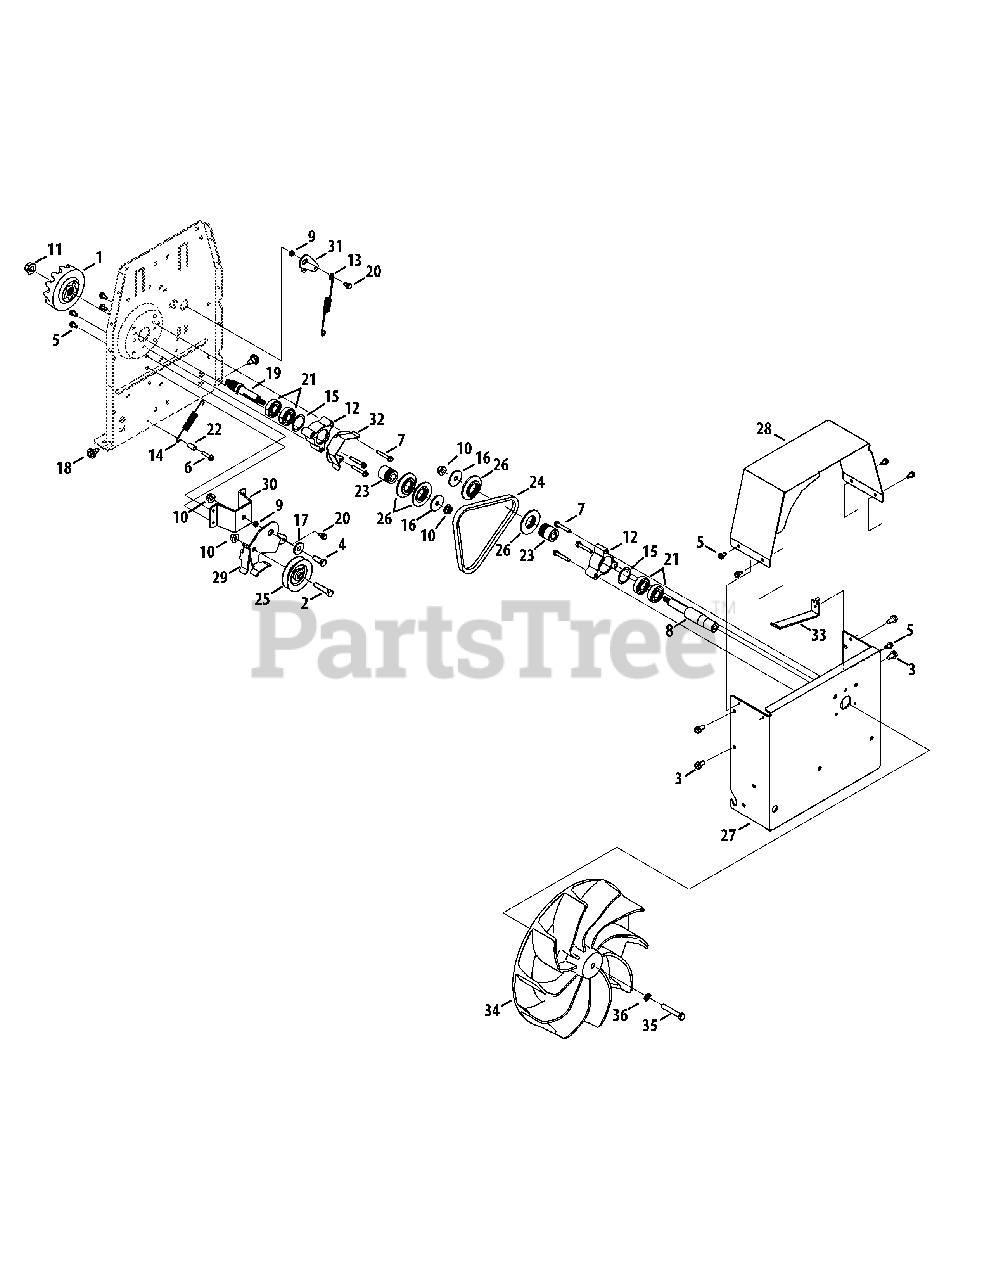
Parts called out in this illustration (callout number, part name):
1	Clutch Assembly
2	Hex Cap Screw, 3/8-16 x 1.75
3	Hex Washer Screw, 5/16-18 x .750
4	Hex Cap Screw, 3/8-16 x 1.0
5	Hex Washer Screw, 1/4-20 x .500
6	Self-tapping Screw, 1/4-20 x 1.00
7	Self-tapping Screw, 1/4-20 x 1.625
8	Spindle Shaft
9	Hex Lock Nut, 1/4-20
10	Flange Lock Nut, 3/8-16
11	Flange Lock Nut, 1/2-13
12	Bearing Cup
13	Extension Spring, .52 OD x 6.1
14	Extension Spring, .500 Dia. x 4.233
15	Washer, 1.25 x 1.57 x .01
16	Washer, Flat, .406 x 1.5 x .105
17	Shoulder Spacer, .625 x .169
18	Shoulder Screw, .43 x .29, 5/16-18
19	Drive Spindle
20	Shoulder Screw, 1/4-20 x .3175 x .188
21	Ball Bearing, 17 x 40 x 12
22	Spacer, .260 x .375 x .75
23	Spacer, .670 ID x 1.185 OD
25	Idler Pulley, V-Type x 3.06
26	Pulley Half, 4L-V x 2.30 OD
28	Blower Top Cover Bracket
29	Blower Drive Idler Bracket
30	Idler Mounting Bracket
31	Cable Engagement Bracket
32	Drive Input Keeper Bracket
33	Drive Output Keeper Bracket
34	Blower Impeller Assembly
35	Hex Cap Screw, 3/8-24 x 2.25
36	Lock Washer, 3/8
